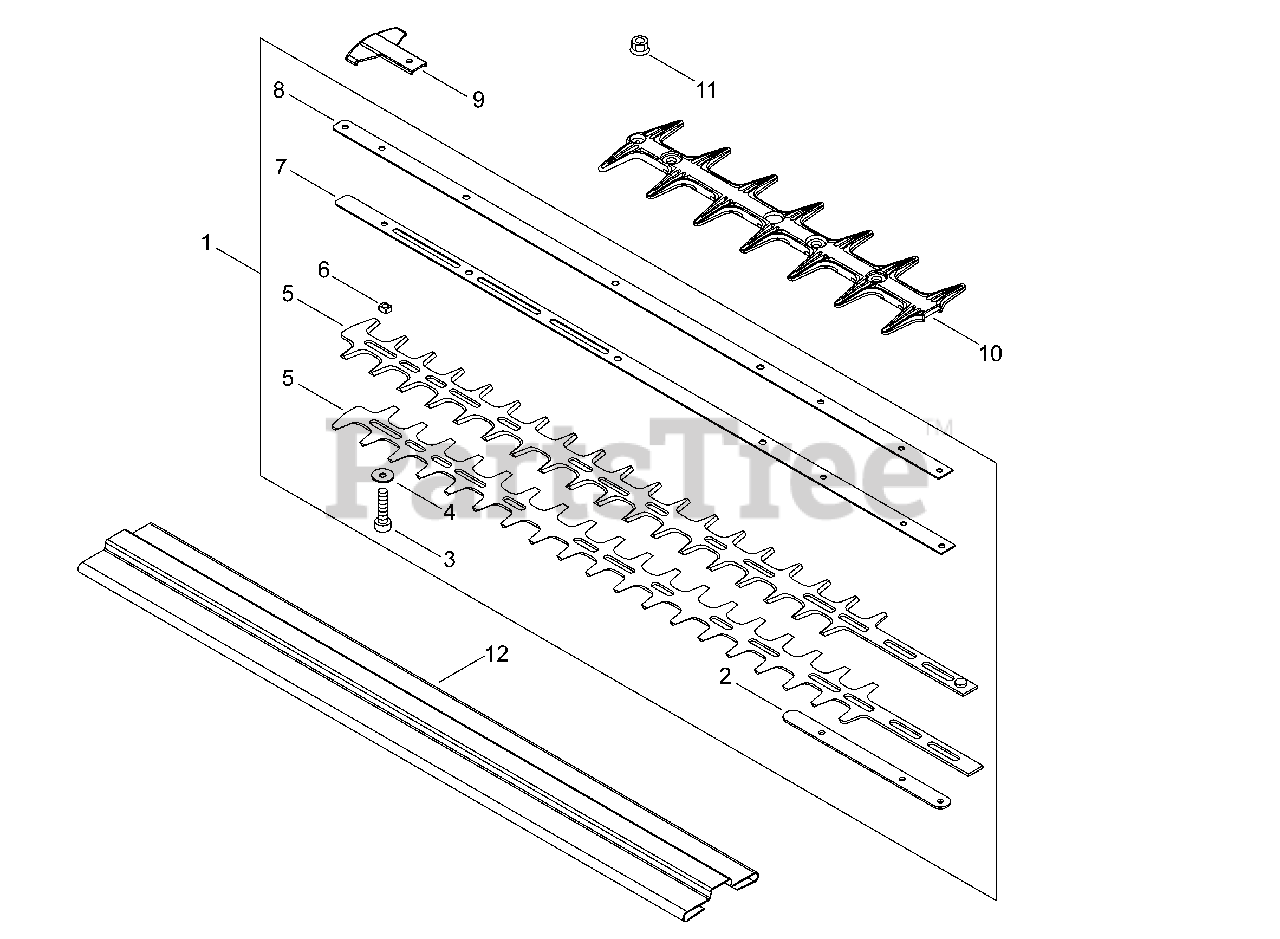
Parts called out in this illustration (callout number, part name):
1	CUTTER,ASM
2	PLATE,EYE
3	BOLT, TORX 5
5	BLADE, TRIMMER
7	SUPPORT,CUTTER
8	SUPPORT,CUTTER
9	TIP GUARD
11	NUT, FLANGE
12	SCABBARD,BLADE
